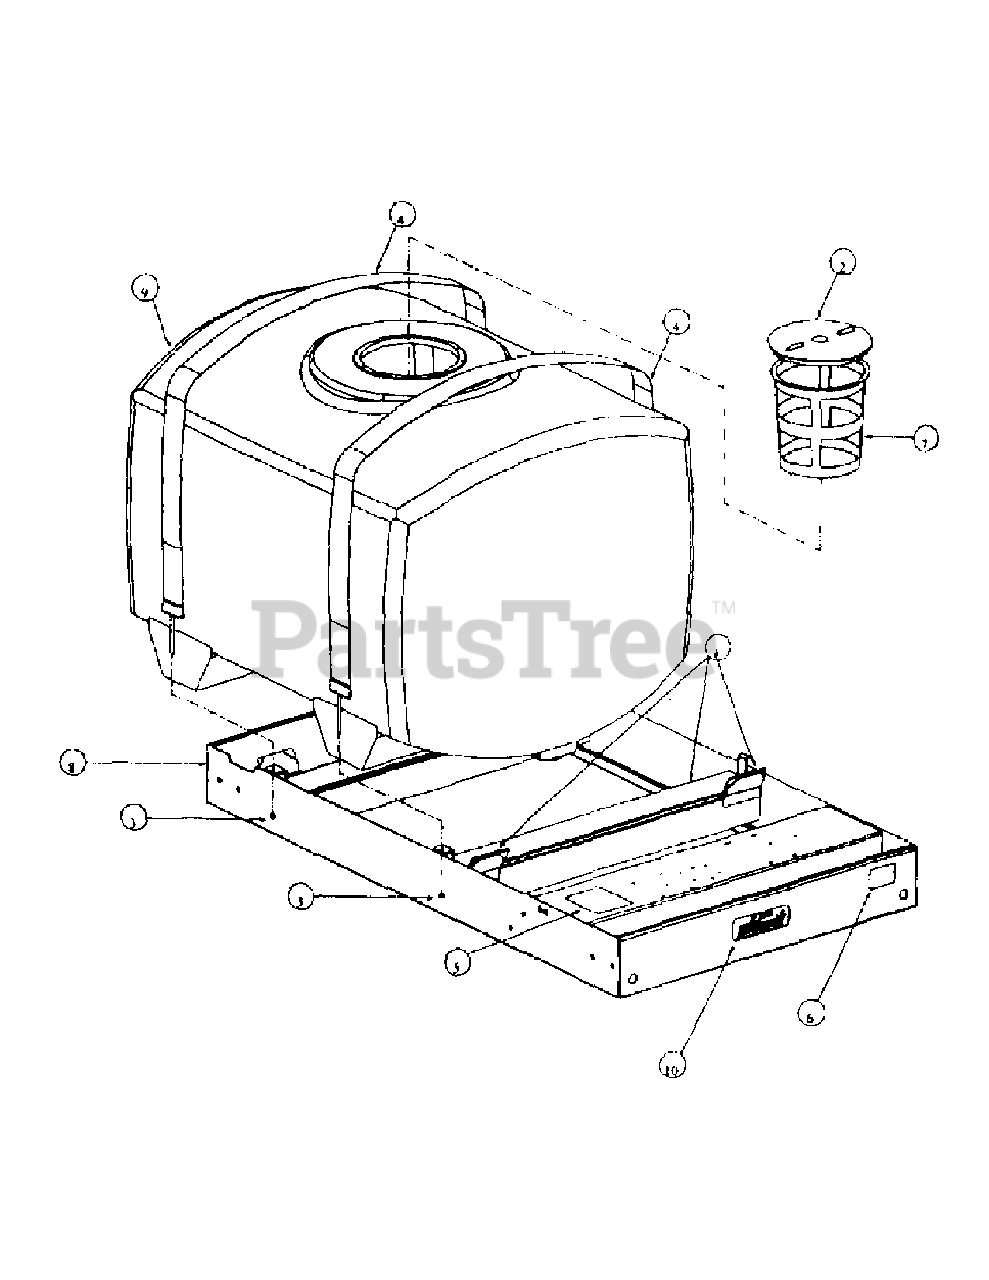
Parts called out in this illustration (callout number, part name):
1	Foam, Adhesive Backed, 4" x 1/4" by ft.
2	Tank, Lid
3	Nut, Nylock 5/16 - 18
4	Tank Strap Assembly
5	Decal Safety Procedures
6	Decal "Made in America"
7	Strainer Basket, 10"
8	Main Frame Assembly
9	200 Gallon Tank Assembly
10	Decal, "Sy 200PE", 2-1/4" x 7"
